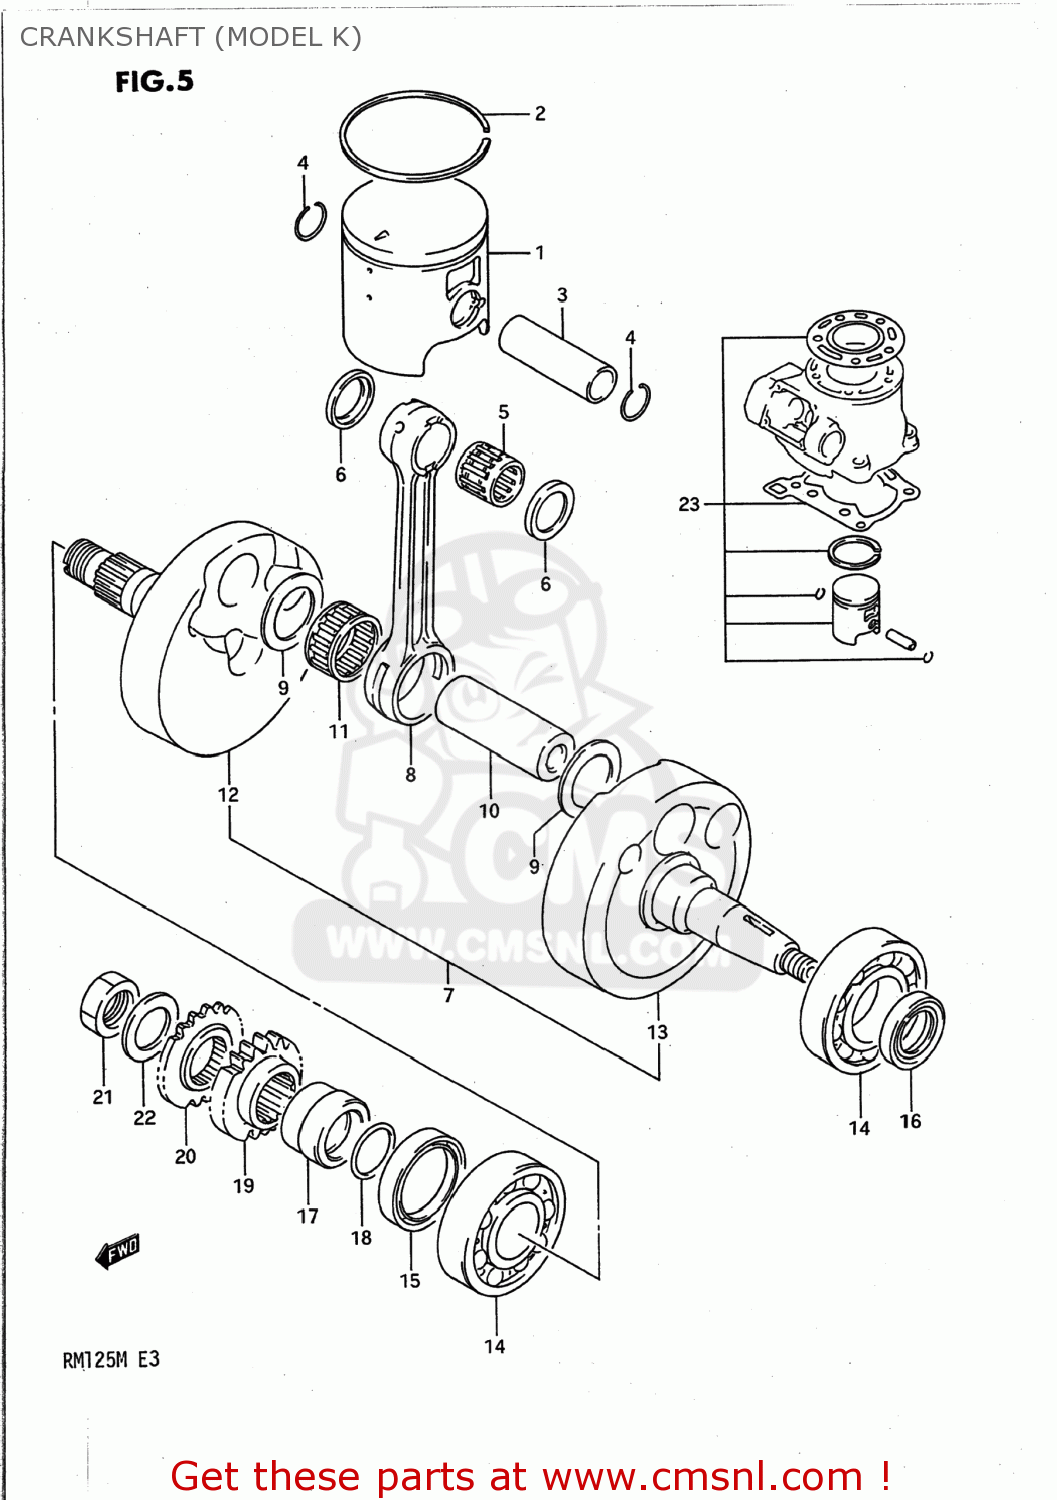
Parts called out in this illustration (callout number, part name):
1	PISTON
2	RING,PISTON
3	PIN,PISTON
4	CIRCLIP
5	BEARING(15X19X20)
6	WASHER
7	CRANKSHAFT ASSEMBLY
8	ROD,CONNECTING
9	WASHER
10	PIN,CRANK
11	ROLLER BEARING (22X28X1
12	CRANKSHAFT,RIGHT
13	CRANKSHAFT,LEFT
14	BEARING
15	OIL SEAL
16	SEAL,OIL(18X30X6)
17	SPACER,PRIMARY DRIVE GEAR
18	O RING(D:2.4,ID:19.8)
19	GEAR,PRIMARY DRIVEN
20	GEAR, GOVERNOR DRIVE (NT:19)
21	NUT
22	WASHER
23	PISTON SET
